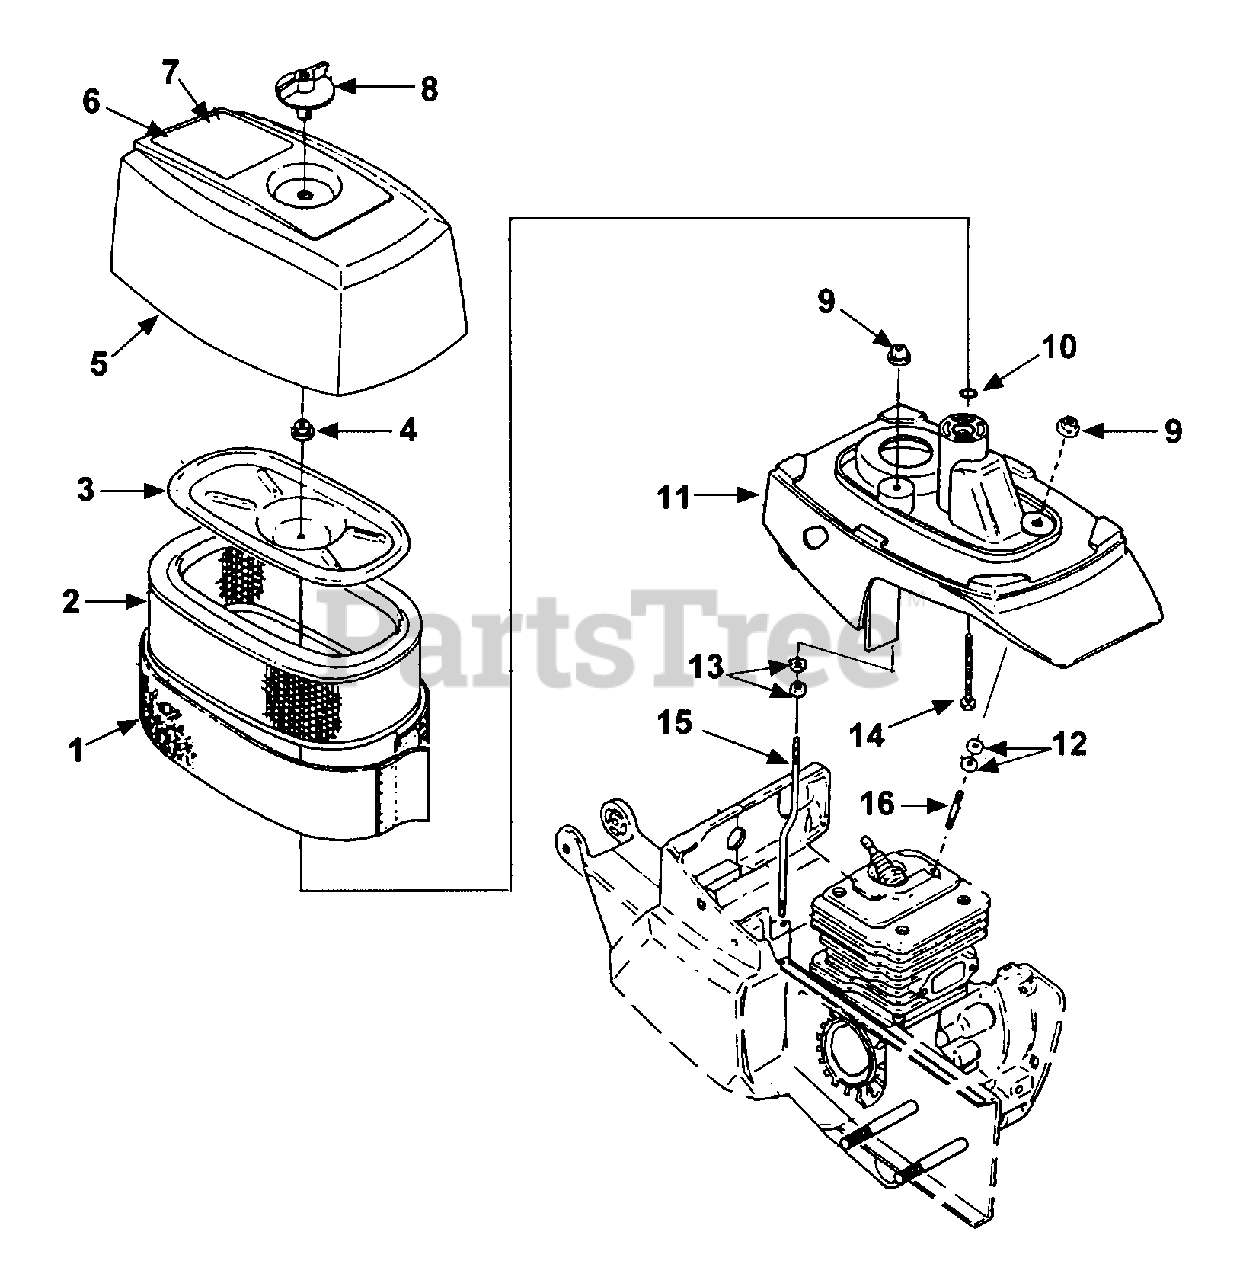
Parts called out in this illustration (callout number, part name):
1	PREFILTER-Felt
2	ELEMENT-Air Filter
3	COVER-Air Filter Element
4	NUT-Hex Conical
5	COVER-Air Filter
6	DECAL-Warning (French)
7	DECAL-Warning (Eng.)
8	KNOB & INSERT
9	NUT- Hex
11	COVER-Cylinder
12	SPACER-Insulating
13	NUT-Hex
14	SCREW-Hex Cap (10-24 X 1 3/4")
15	STUD-Offset (10-24)
16	STUD (10-24 x 1")
